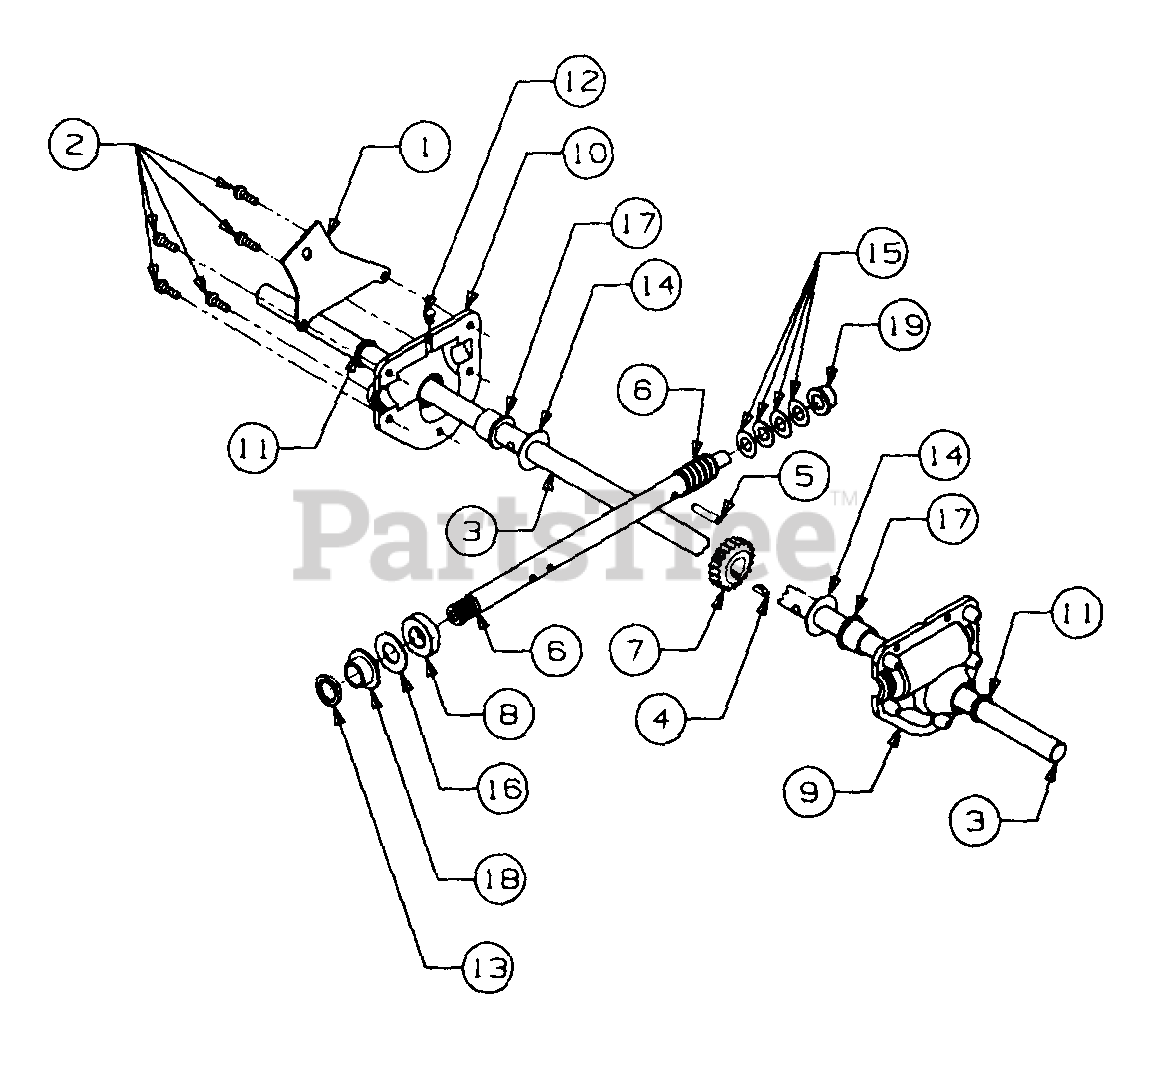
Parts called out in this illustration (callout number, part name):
2	Screw, Hex Wash TT-Tap, 1/4-20 X .75 Lg
3	Shaft, Auger
4	Key, Hi-Pro,3/16 X 5/8
5	Pin, Spirol Spring, 1/4 Dia X 1.25 Lg
6	Shaft,Impeller
7	Gear, Worm
8	Collar, Thrust
9	Housing, RH Auger Gear
10	Housing, LH Auger Gear
11	Seal, Oil
13	Seal, Oil .75 X 1.131 X .188 Thk
14	Washer, Flat, .760 X 1.50 X .030 Thk
15	Washer, Flat, .580 X 1.00 X .020 Thk
16	Washer, Flat, .760 X 1.50 X .060 Thk
17	Bearing, Flange, .754 ID X 1.00 OD X .925 Lg
18	Bearing, Flange, .75 ID X 1.00 OD X .59 Lg
19	Bearing, Flange, .502 l D X .751 OD X .59 Lg
